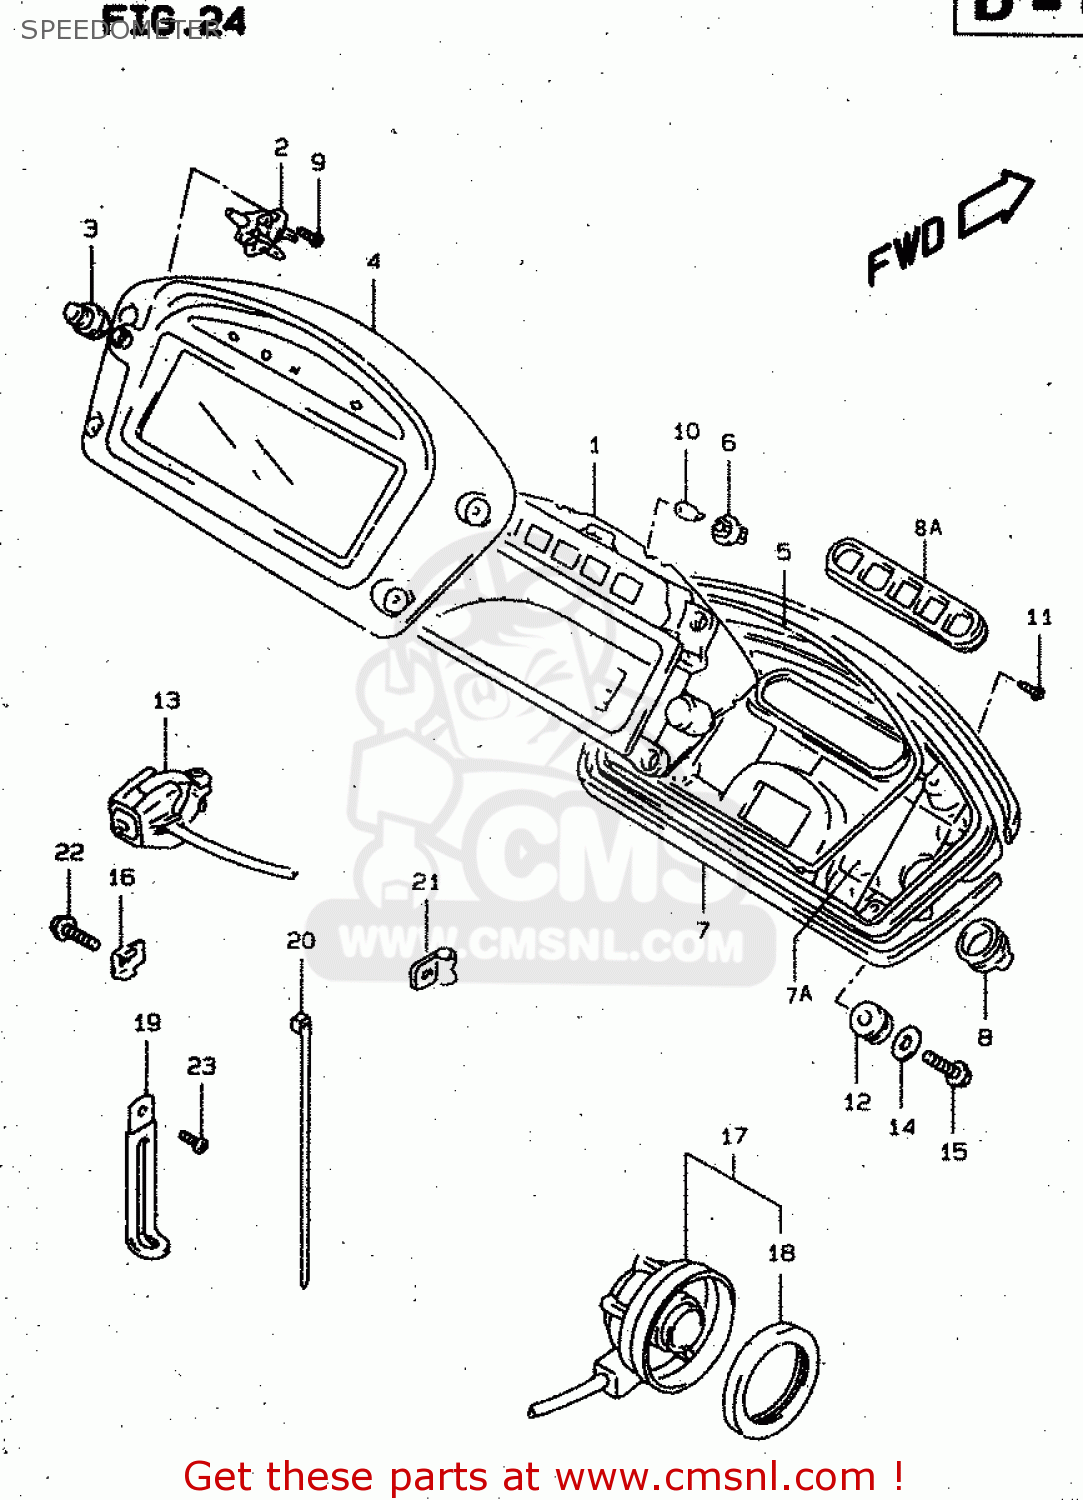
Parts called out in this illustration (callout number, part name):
1	SPEED & TACHOMETER ASSY
2	ATTACHMENT,SWITCH
3	SWITCH,GUM
4	VISOR
5	PACKING
6	SOCKET(T:6.5)
7	PACKING
7A	CASE
8	CAP,BLIND NO.1
8A	CAP,BLIND
9	SCREW(3X10)
10	BULB(12V1.7W,T6.5)
11	SCREW
12	CUSHION,METER
13	SWITCH ASSY,SPEEDOMETER
14	WASHER(5.5X16X1.2)
15	SCREW
16	GUIDE,SENSOR LEAD
17	SENSOR ,SPEED
18	OIL SEAL (43X58X7)
19	CLAMP(L:65)
20	CLAMP(L:145)
21	CLAMP
22	BOLT
23	SCREW 6X10
